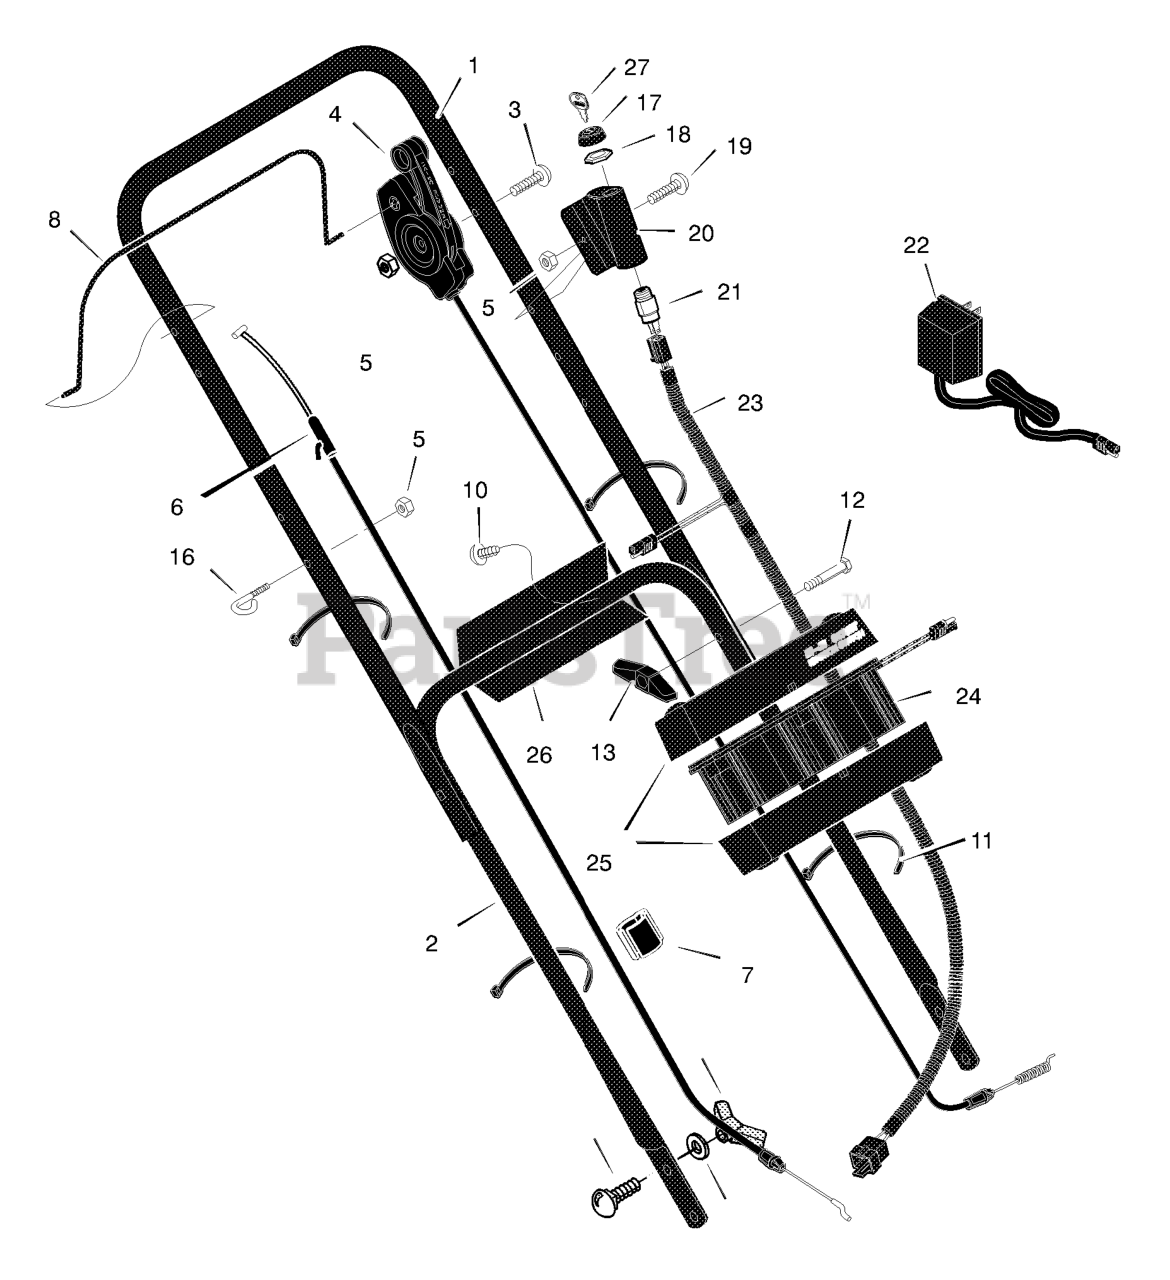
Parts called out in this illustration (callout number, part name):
1	Handle, Upper (Gray)
2	Handle, Lower (Gray)
4	Control, Drive
5	Locknut
6	Cable, Stop
7	Fastener, Cable
8	Lever, Stop
11	Fastener, Cable
13	Knob
16	Guide, Rope
17	Cap
18	Nut
20	Cover, Ignition
21	Switch Ignition & Key
22	Charger, Battery
23	Harness, Wiring
24	Battery
25	Case, Battery
26	Bracket, Battery
27	Key, Ignition
29	Bolt, Carriage
31	Knob, Plastic
